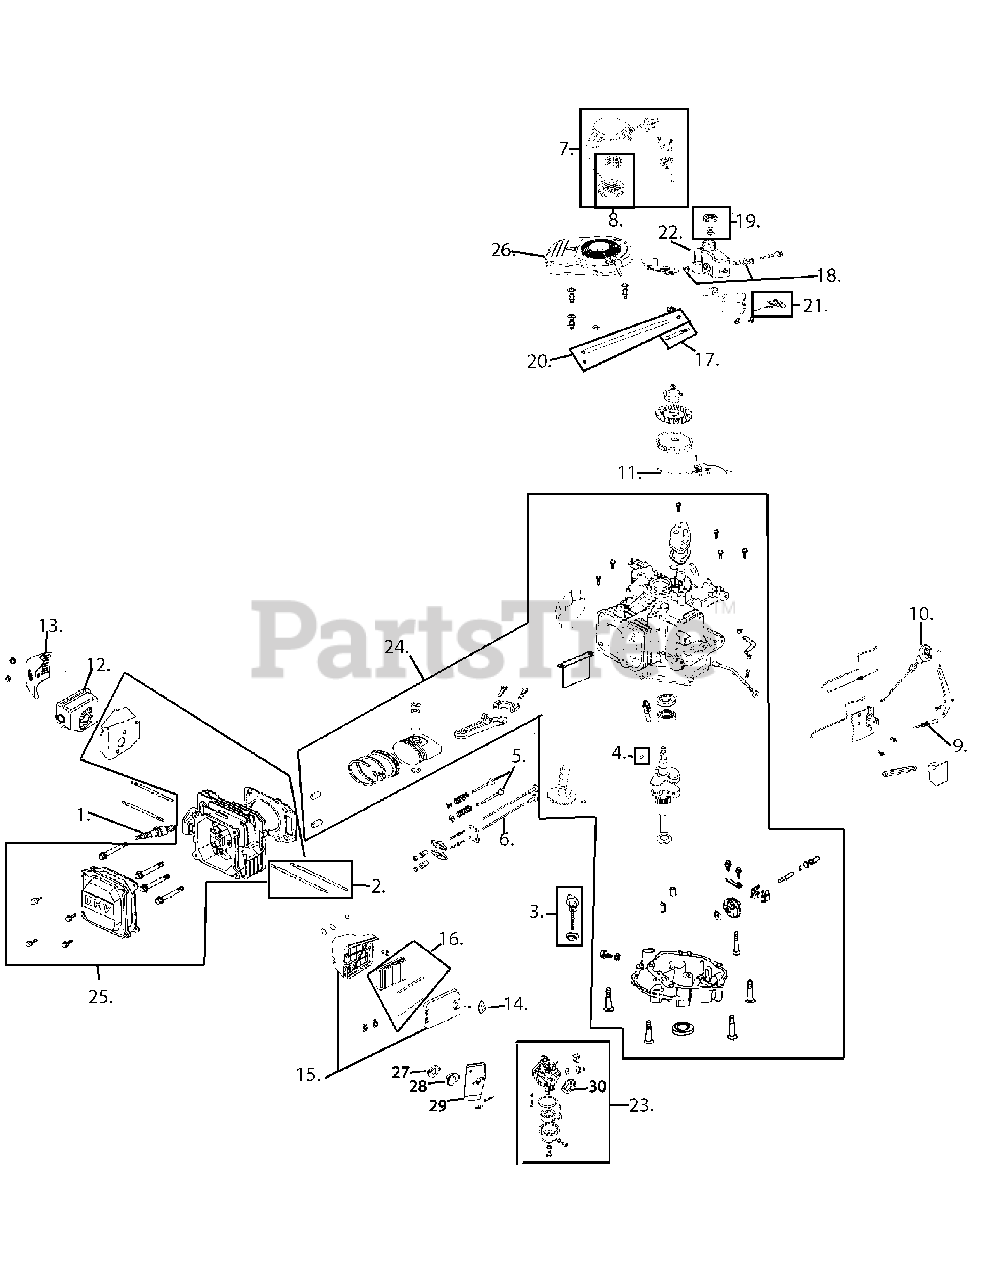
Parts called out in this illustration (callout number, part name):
1	Spark Plug
2	Muffler Stud Assembly
3	Dipstick Assembly
4	Flywheel Key
5	Valve Kit
6	Push Rod Kit
7	Recoil Starter Assembly
8	Recoil Spring & Pulley Assembly
9	Governor Return Spring
10	Choke Control Knob
11	Ignition Coil
12	Muffler Assembly
13	Muffler Shield
14	Air Cleaner Thumb Screw
15	Air Cleaner Housing Assembly Complete
16	Air Cleaner Kit
17	Fuel Filter
18	Rubber Fuel Tank Mounting Washer
19	Fuel Cap Assembly
20	Fuel Line Kit
21	Ignition Switch
22	Fuel Tank
23	Carburetor Assembly
24	Short Block Assembly
25	Cylinder Head Assembly
26	Engine Shroud - Black
27	Carb Insulator Gasket
28	Carb Insulator
29	Carb Gasket
30	Carb Gasket Plate
